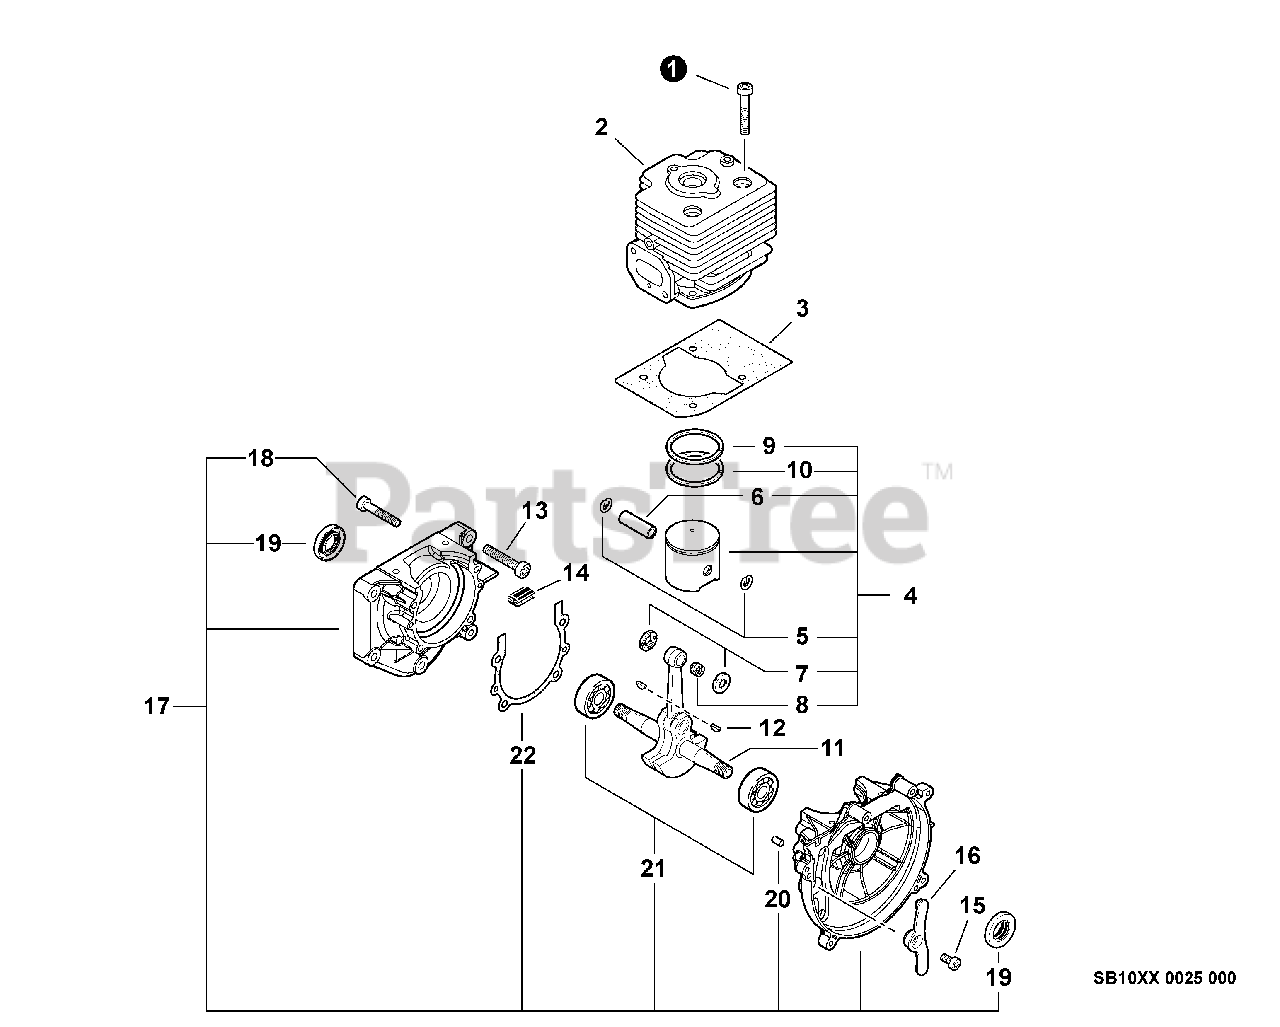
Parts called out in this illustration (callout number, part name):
1	BOLT, TORX 5×25
2	CYLINDER
3	GASKET, CYLINDER
4	PISTON KIT
5	RING, SNAP 8
6	PIN, PISTON
7	WASHER, THRUST
8	BEARING, NEEDLE 10
9	RING, PISTON
10	RING, PISTON
11	CRANKSHAFT ASSY
12	KEY, WOODRUFF 3×14
13	BOLT, TORX 6×30
14	COVER, DUST
15	BOLT, TORX 5×10
16	COVER, DUST
17	CRANKCASE KIT
18	BOLT, TORX 5×30
19	SEAL, OIL 15
20	PIN, LOCATING 4×8
21	BEARING, BALL 6302
22	GASKET, CRANKCASE
